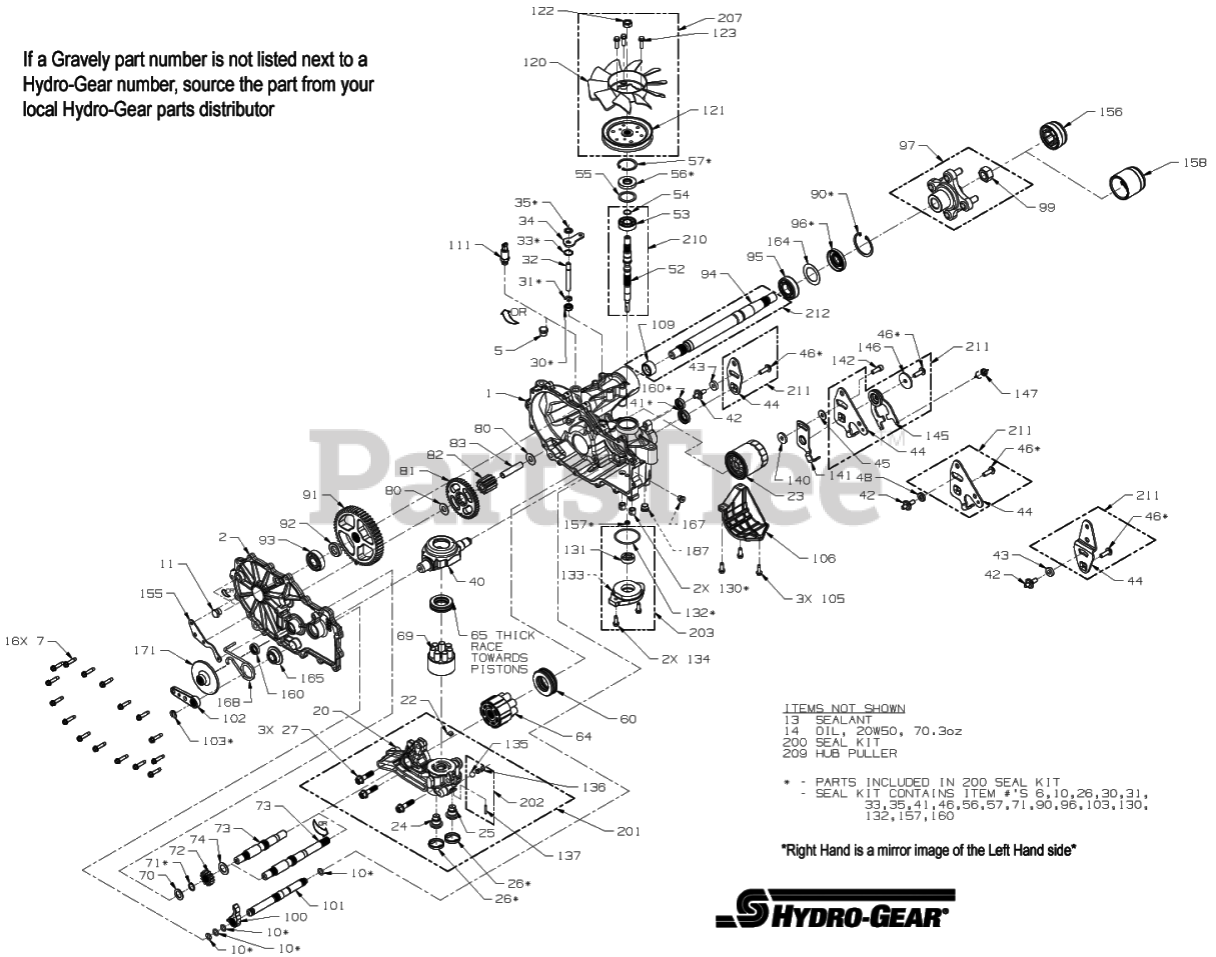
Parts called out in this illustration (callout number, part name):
1	KIT, HOUSING, MAIN, RH, CHRG, CNTL
2	KIT, COVER, SIDE, RH
7	SCREW,HEX WASHER 1/4-20X1.125
13	SEALANT TUBE 10.1OZ.
22	PLATE, BYPASS
23	OIL FILTER, TRANSMISSION
26	SEAL, PLUG 1.375 X .250
30	SEAL, LIP .375X.75X.25
31	RING. RETAINING
32	ROD, BYPASS
33	RING, RET .750
34	ARM, BYPASS
35	RING, RTNG .
40	TRUNNION, SWASHPLATE
41	SEAL, LIP 18X32X7
45	WASHER
46	TWHCS 5/16-24 X 1.00
55	WASHER 1.23X1.56X.04
56	SEAL, LIP 17X40X7
57	RING, RET 1.56 INT
60	HG THRUST BEARING (51462)
64	HG 16CC CYLINDER BLOCK (71579)
65	BEARING. THRUST 30 X 52 X 13
69	ASSY, BLOCK 7 PISTON
70	WASHER .63X1.0X.05
71	RING, RET 62 EXT
73	SHAFT, MOTOR
74	WASHER .71 X 1.16 X .04
80	WASHER .5X1.0X.032
83	JACK SHAFT (PIN)
90	RING, RETAINING
95	BEARING, BALL 25.4 X 52 X 15
96	SEAL, LIP
97	KIT, HUB 4 BOLT
99	NUT, HEX, LOCK 3/4-16
100	PAWL, BRAKE
101	SHAFT, BRAKE
102	BRAKE ARM HYRDROGEAR 52499
103	RING, RETAINING
105	HFHCS 1/4-20X.75
106	GUARD, FILTER, RH
111	KIT, FITTING 1/2 BEADED 9/16
120	FAN, 7.0 W/INSERT
121	DISC, PULLEY, CUPPED, 4.5 INCH
122	NUT, HEX 1/2-20 PATCH
124	HUB, PULLEY
130	TUBE, CONNECTING
131	GEROTOR
132	O-RING HYDROGEAR 52250
133	COVER, CHARGE PUMP
134	HFHCS 1/4-20X.75
140	SPACER
141	ARM, NEUTRAL RIGHT
142	SHCS 5/16-24X1 PATCH
147	SPRING, HYDROGEAR P/N 51833
157	KIT, GEROTOR SEAL
158	CAP, AXLE
186	TUBE, AXLE
200	KIT, SEAL
201	KIT, CENTER SECTION RH, CHRG
202	KIT, CHARGE RELIEF
203	KIT, CHARGE
207	KIT, FAN/PULLEY
209	HUB PULLER 4 BLT HYDGEAR 71459
210	INPUT SHAFT 2800 HYDGEAR 71442
211	KIT, RTN CW
212	KIT, SHAFT, AXLE
